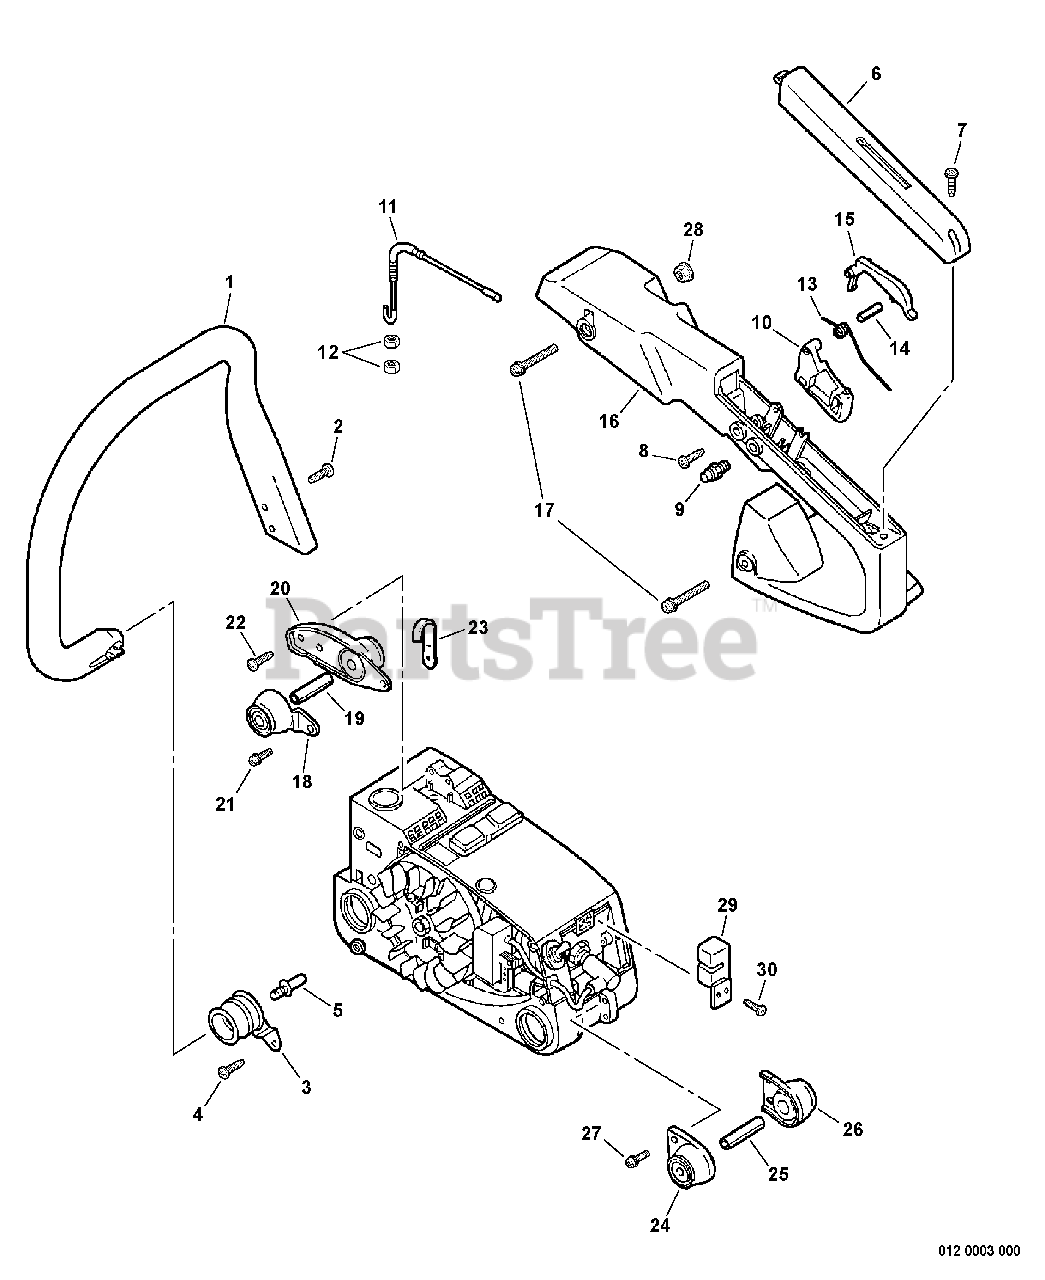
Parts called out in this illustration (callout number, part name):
1	HANDLE, FRONT
2	SCREW, TAPPING 5×20
3	CUSHION 5
4	SCREW 4×16
6	COVER, HANDLE
7	SCREW 4×22
8	SCREW 4×25
9	LOCK, THROTTLE TRIGGER
10	CONTROL, THROTTLE
11	CABLE, THROTTLE
13	SPRING, THROTTLE LOCKOUT
14	ROLLER, 4×19.8
15	LOCKOUT, THROTTLE
16	HANDLE, REAR
17	SCREW 5×57
19	COLLAR 5
20	CUSHION
21	SCREW 4×10
22	SCREW 4×14
25	COLLAR 5
27	SCREW 4×14
28	NUT, FLANGE M5
30	SCREW 4×14
